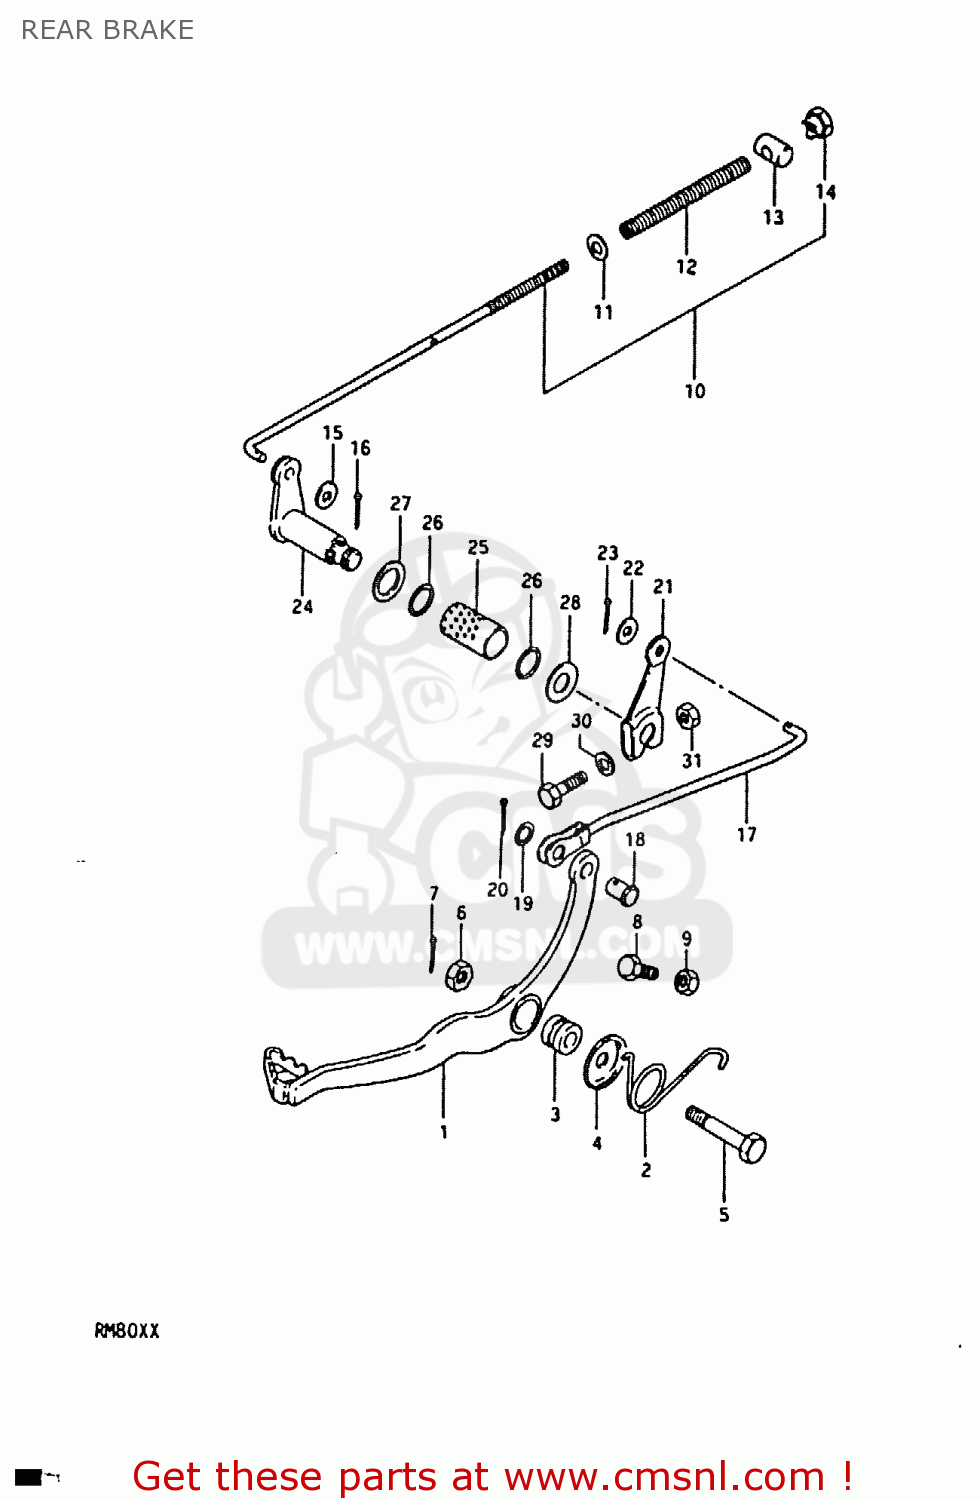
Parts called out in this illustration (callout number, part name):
1	PEDAL,BRAKE
2	SPRING
3	SPACER,BRAKE PEDAL
4	WASHER,BRAKE PEDAL
5	BOLT 8X50
6	NUT 8MM
7	PIN 20X20
8	BOLT(6X23)
9	NUT
10	ROD ASSY,RR BRAKE RR
11	WASHER
12	SPRING
13	PIN(11X18)
14	NUT
15	WASHER
16	PIN 20X20
17	ROD, REAR BRAKE FRONT
18	PIN
19	WASHER
20	PIN 20X20
21	ARM,REAR BRAKE ROD,OUTER
22	WASHER
23	PIN 20X20
24	ARM, REAR BRAKE INNER
25	BUSHING,REAR BRAKE ROD ARM
26	O RING(D:1.7,ID:15.5)
27	WASHER
28	WASHER
29	BOLT
30	WASHER
31	NUT
